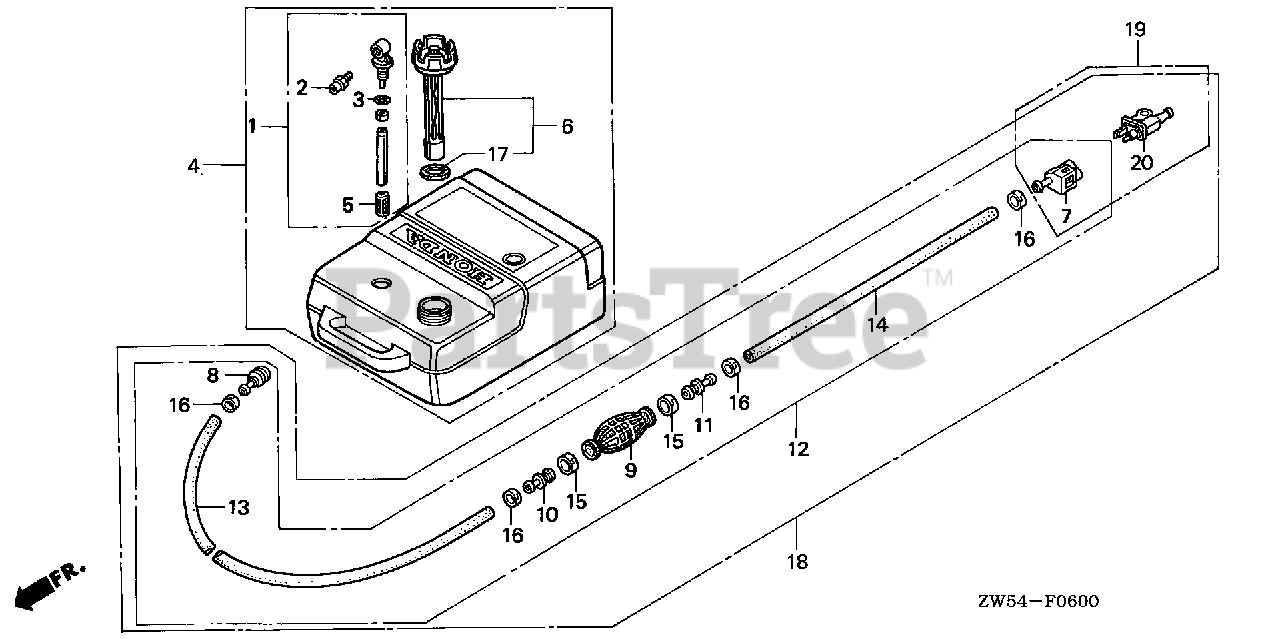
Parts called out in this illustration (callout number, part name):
1	JOINT ASSY., FUEL Use up to Frame SN 1303827.
1	JOINT ASSY., FUEL Use from Frame SN 1303828.
2	FITTING, QUICK DISCONNECT
3	O-RING Use up to Frame SN 1303827.
3	O-RING Use from Frame SN 1303828.
4	TANK ASSY., FUEL
5	FILTER, FUEL Use up to Frame SN 1303827.
5	FILTER, FUEL
6	CAP, FUEL FILLER Use up to Frame SN 1303827.
6	CAP, FUEL FILLER
7	CONNECTOR ASSY., FUEL (A)
8	CONNECTOR, FUEL
9	BULB, PRIMER
10	VALVE, IN.
11	VALVE, OUTLET
12	TUBE ASSY., FUEL
13	TUBE, FUEL LONG (7.3X2000)
14	TUBE, FUEL SHORT (6.3X500)
15	BAND, TUBE CLIP (20MM)
16	BAND, TUBE CLIP (12.5MM)
17	GASKET, FUEL CAP Use up to Frame SN 1303827.
17	GASKET, FUEL CAP Use from Frame SN 1303828.
20	CONNECTOR ASSY., FUEL (B)
